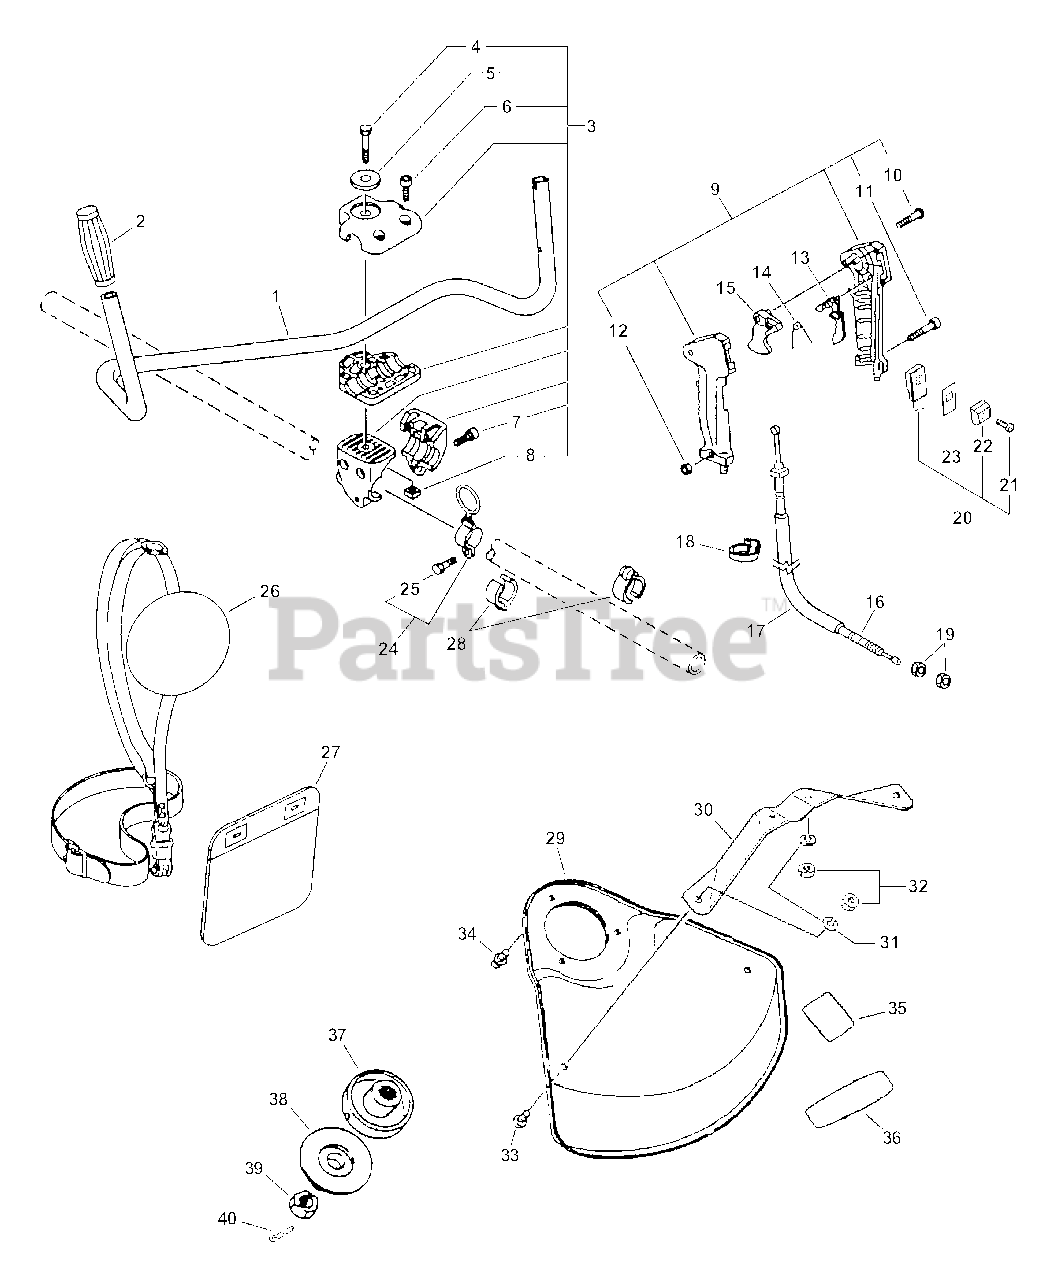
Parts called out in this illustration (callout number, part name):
1	HANDLE - FRONT
2	GRIP, HANDLE - LEFT
3	HANDLE BRACKET KIT
4	BOLT - 8X55
5	WASHER - 8
6	SCREW - 5X20
7	SCREW - 5X30
9	THROTTLE CONTROL ASSY
10	SCREW - 3X25
11	SCREW - 5X30
13	LOCKOUT, THROTTLE
14	SPRING, LOCKOUT LEVER
15	TRIGGER, THROTTLE
16	CABLE, THROTTLE
17	TUBE, PROTECTIVE - CORRUGATED
20	IGNITION SWITCH ASSY
21	SCREW - 3X10
22	KNOB, SWITCH - ORANGE
23	COVER, SWITCH - STOP
24	HANGER KIT
25	BOLT - 5X12
26	HARNESS ASSY
27	CUSHION
29	SHIELD, DEBRIS - METAL
30	BRACKET, SHIELD
31	LOCKWASHER - 5
33	SCREW - 5X8
34	SCREW - 5X10
35	LABEL - ECHO
36	LABEL - DANGER
37	ADAPTOR, BLADE - UPPER
38	ADAPTOR, BLADE - LOWER
39	NUT - 10 -- LEFT HAND
40	PIN, SPLIT - 2X22
